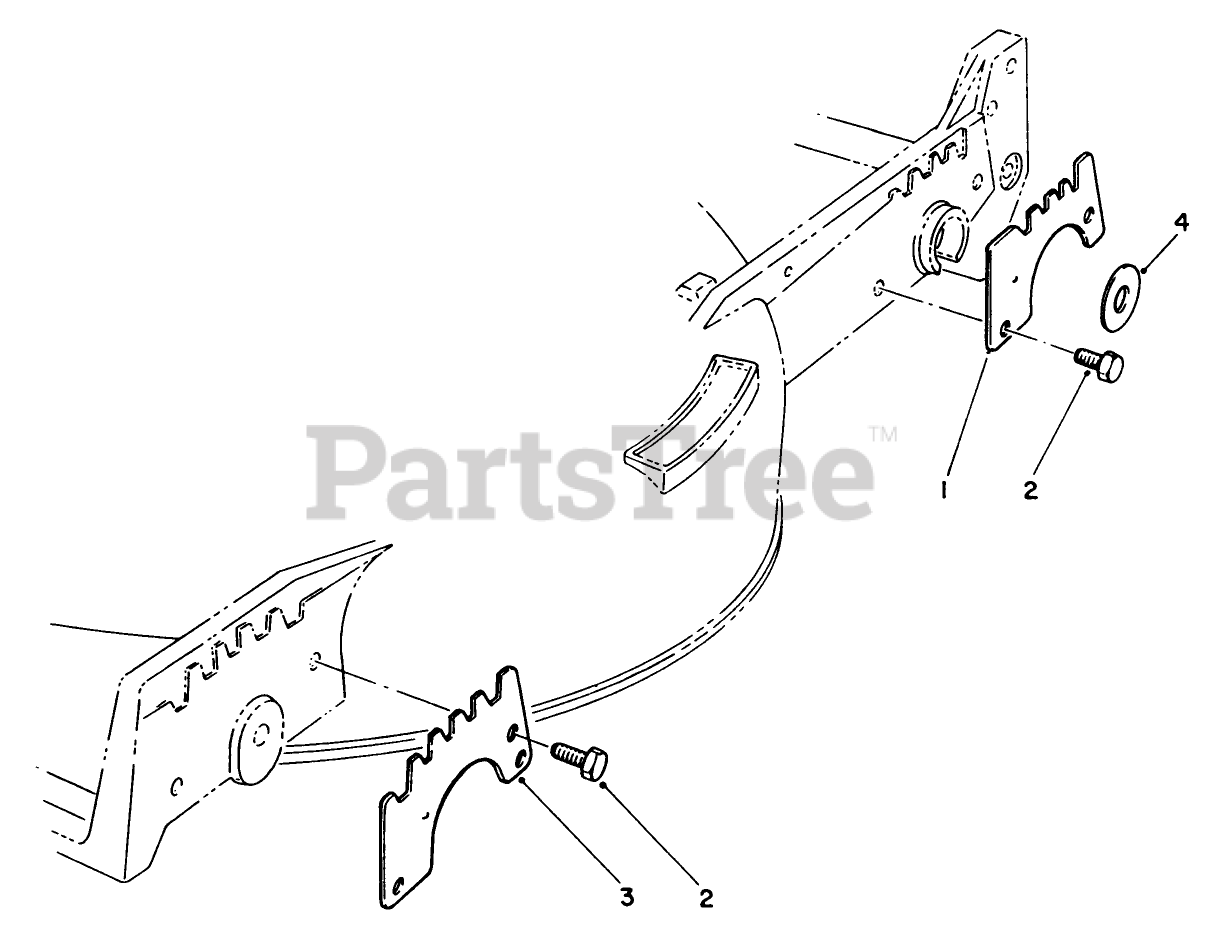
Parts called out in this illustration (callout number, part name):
1	WEAR PLATE,REAR
2	SCREW-HWH
3	WEAR PLATE
4	PIVOT WASHER
